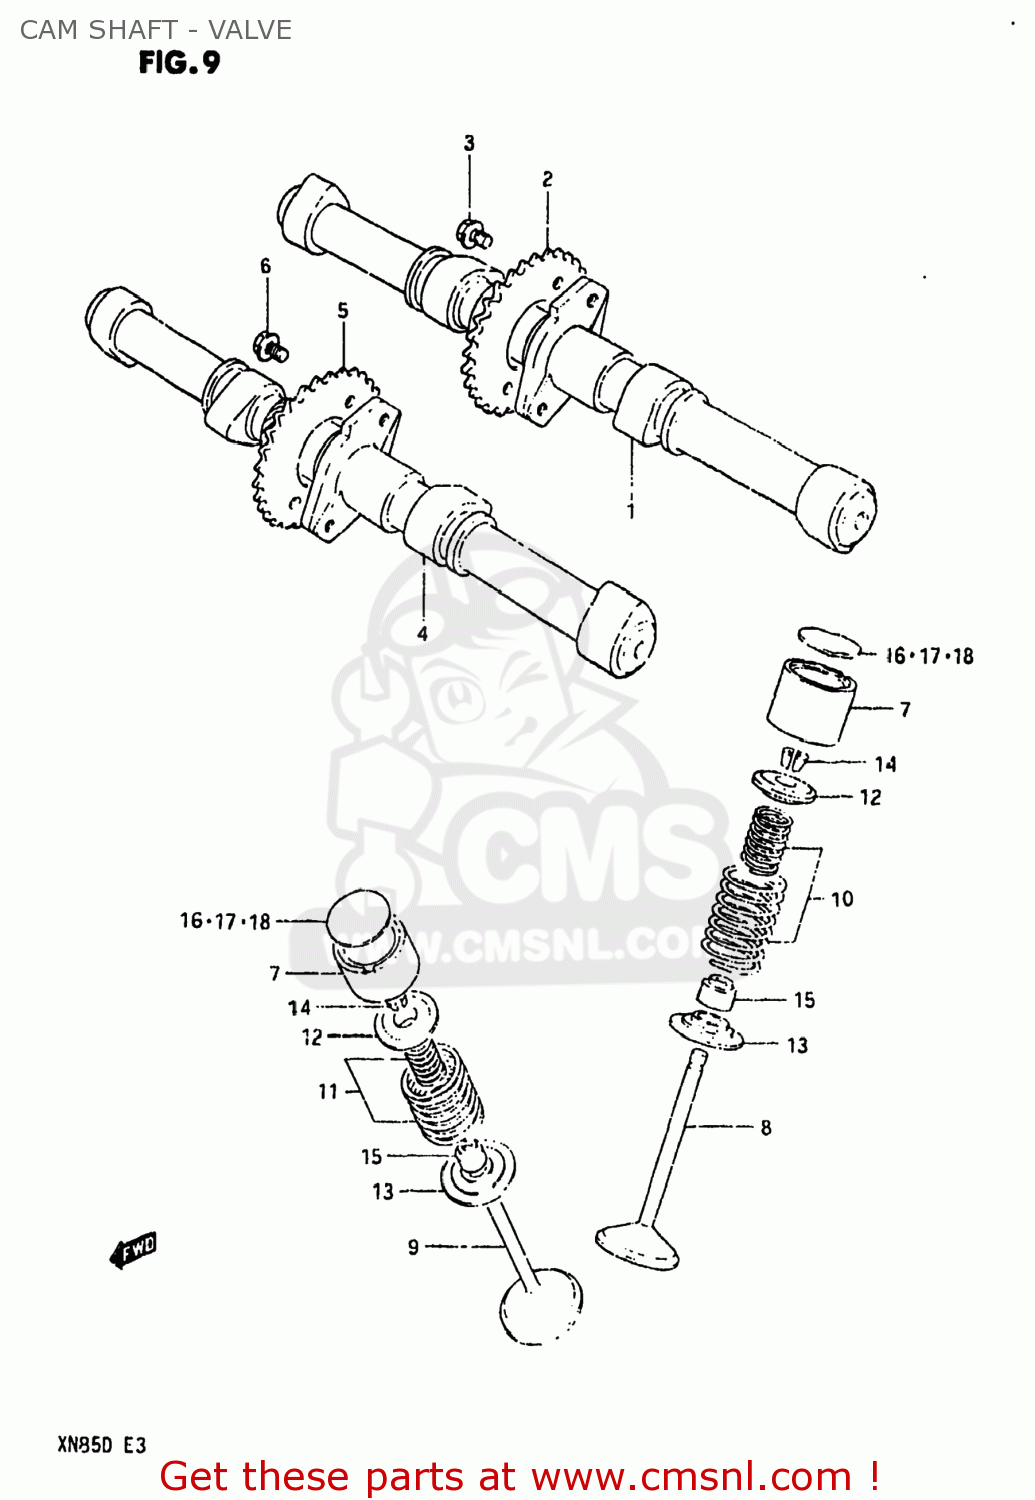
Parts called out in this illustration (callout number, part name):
1	CAMSHAFT,INTAKE
2	SPROCKET,INTAKE CAMSHAFT
3	BOLT(7X11)
4	CAMSHAFT,EXHAUST
5	SPROCKET,EXHAUST CAMSHAFT
6	BOLT(7X11)
7	TAPPET
8	VALVE,INTAKE
9	VALVE,EXHAUST
10	SPRING SET,VALVE
11	SPRING SET,EXHAUST VALVE
12	RETAINER,VALVE SPRING
13	SEAT,VALVE SPRING
14	COTTER VALVE
15	SEAL,OIL(7X14.4X9)
16	SHIM,TAPPET
17	SHIM,TAPPET
18	SHIM,TAPPET
19	SHIM SET,TAPPET
20	CASE
